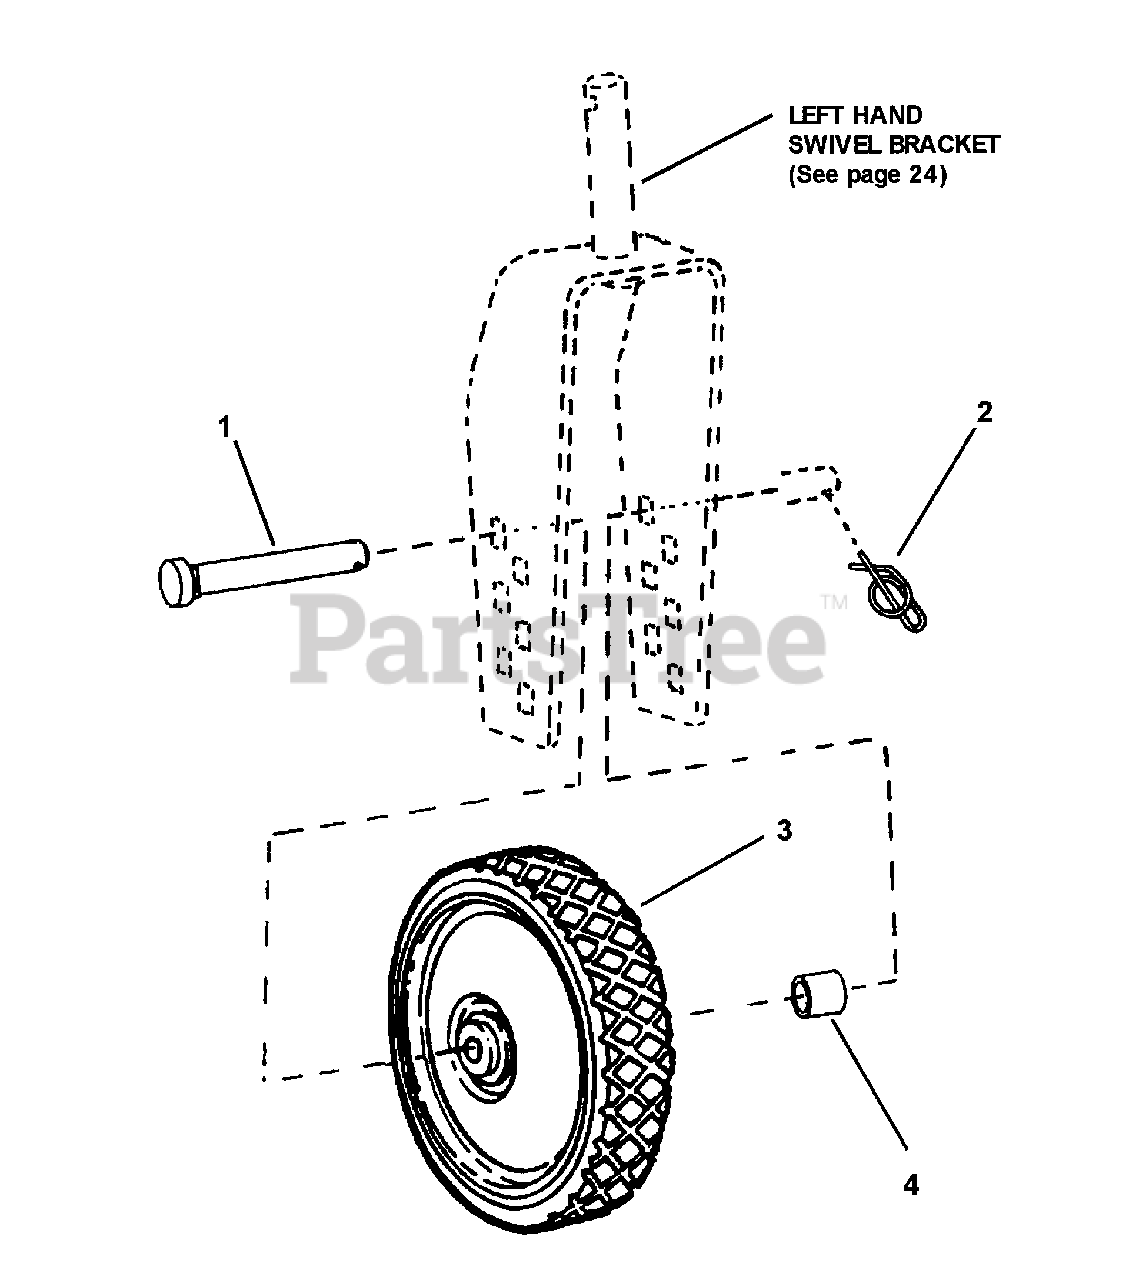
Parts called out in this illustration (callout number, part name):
1	PIN, Wheel 7/16"x 2.75"
2	PIN, Swivel Wheel Lock
3	WHEEL, 8 x 1.75 Steel
4	SPACER, Wheel
